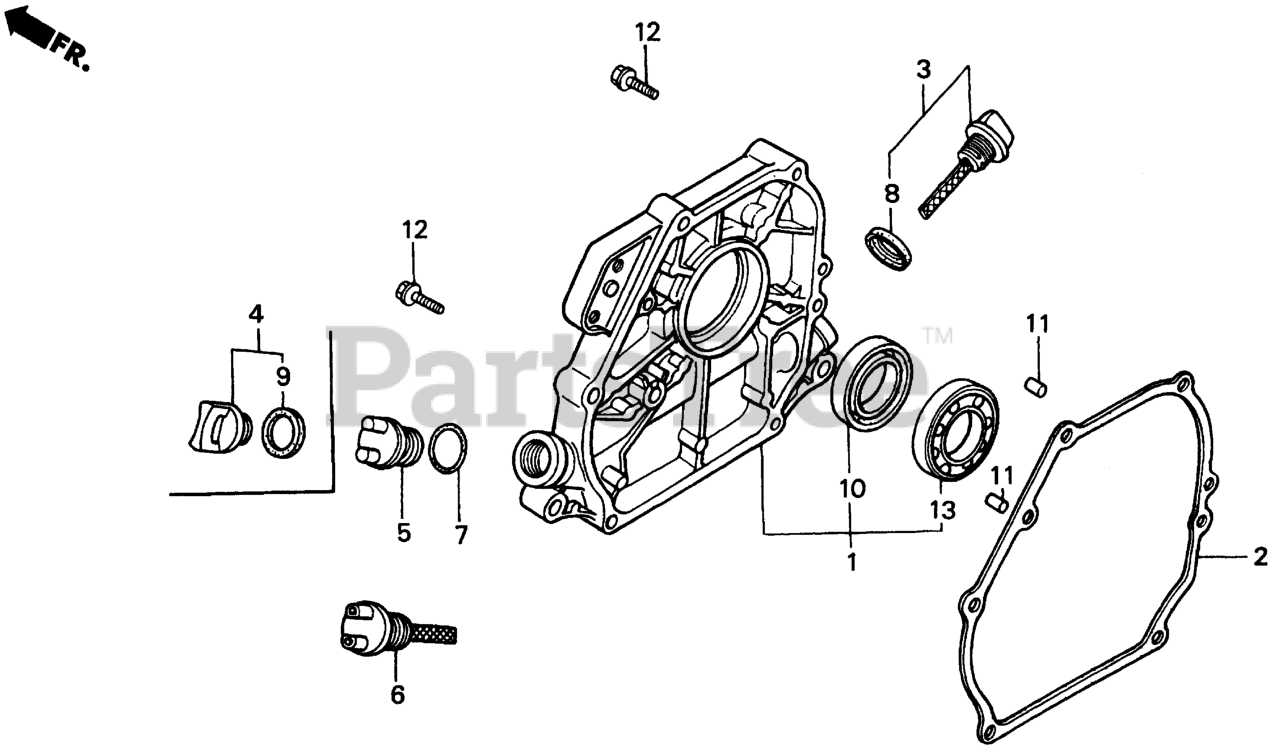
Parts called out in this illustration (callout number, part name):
1	COVER, CRANKCASE
2	GASKET, CASE COVER (NON-ASBESTOS)
3	CAP ASSY., OIL FILLER
5	CAP, OIL FILLER
6	CAP, OIL HOLE
7	GASKET, OIL FILLER CAP Use from Engine SN 1391010.
8	GASKET, OIL FILLER CAP
10	OIL SEAL (25X41X6)
11	PIN A, DOWEL (8X14)
12	BOLT, FLANGE (8X32)
13	BEARING, RADIAL BALL (6205)
